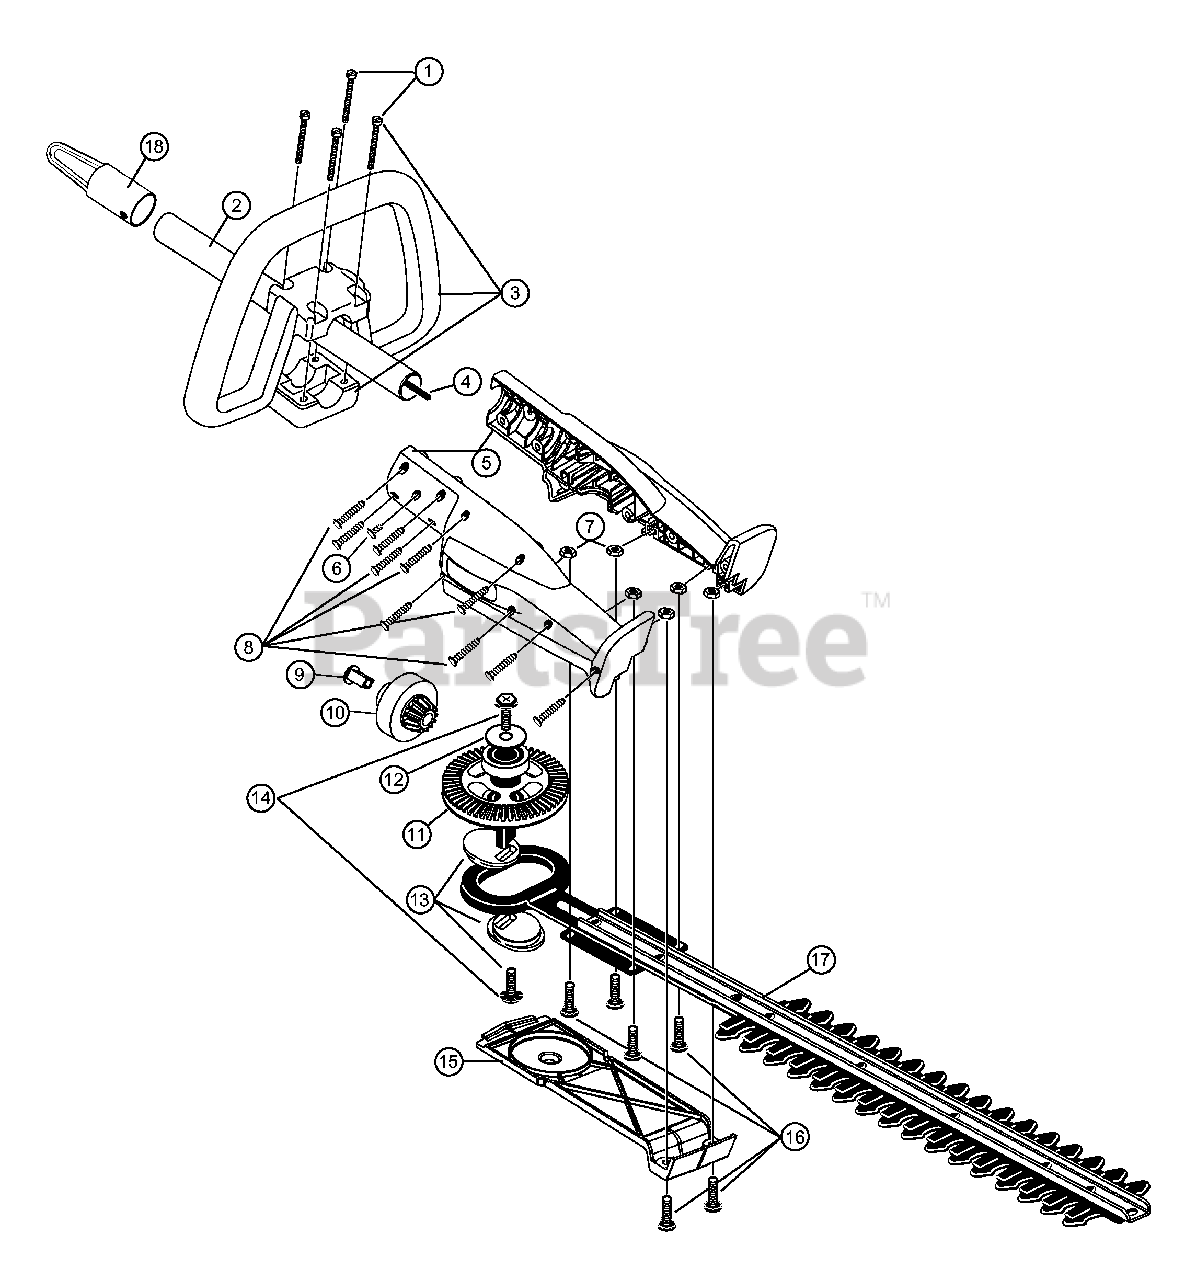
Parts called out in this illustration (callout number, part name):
2	Drive Shaft Housing Assembly
3	Loop Handle Assembly
4	Drive Shaft Assembly
5	Housing Set
6	Anti-Rotation Screw
8	Housing Screw
10	Pinion Gear
11	Bevel Gear Assembly
13	Cam Assembly
15	Bottom Plate
17	Cutting Blade Assembly
18	Hanger
